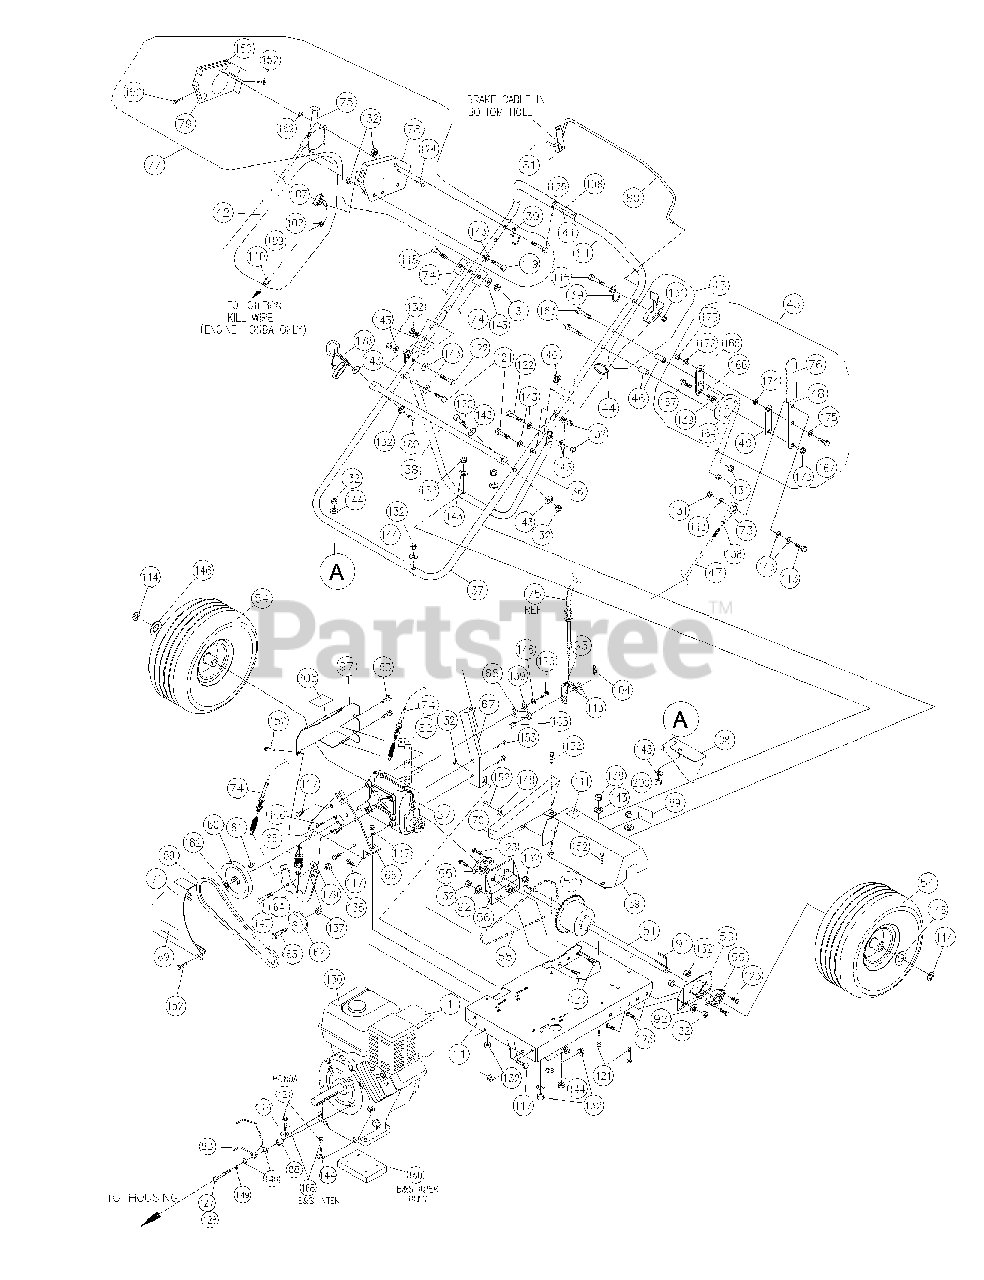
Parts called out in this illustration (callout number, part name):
1	ENGINE 10 HP INTEK B&S
2	ANGLE MOUNT HDLE WA
3	IMPELLER ASSY VQ (INCLUDES ITEM 4,5,6,7)
4	KEY 0.25 SQ. X 2.75"
5	WASHER LOCK 7/16 S/T MED
6	SCREW CAP 7/16 NF x 2 1/4 GR8 TORQ 55-60 FT LBS (75-81 N.m)
7	SPACER ENGINE
9	SCREW CAP 5/16 NF x 2 1/2 GRD. 8
10	HOUSING ASSEMBLY W/LABELS VQ
11	FRAME WA VQ
12	NOZZLE ASSEMBLY VQ
13	NOZZLE ASSY W/LABELS
14	HOSE TUBE PLUG VQ
15	PLATE DOOR NOZZLE HOSE
16	ROD DIVERTER VQ
17	GROMMET FLG. 1/2 MOLDED
18	BRKT BOGIE ASSY LH
19	BRKT BOGIE ASSY RH
20	BRKT BOGIE WA LH
21	BRKT BOGIE WA RH
22	ROLLER GUIDE
23	PIN ROLLER
24	WHEEL BOGIE 3"
25	SPACER 5/16 X 1 5/8
26	CASTER & BRKT LH ASSY SEMI-PNEU VQ
27	CASTER & BRKT RH ASSY SEMI-PNEUVQ
28	BRKT LH WA 8" CASTER
29	BRKT RH WA 8" CASTER
30	CASTER ASSY 8" SEMI-PNEU 3/4 NC (INCL ITEM 33 (4), 94, 95, 125, 134)
31	KNOB HAND
32	NUT WING WA
33	WASHER 3/4 NYLON
34	ELBOW ASSY W/LABELS VQ
35	GASKET FLANGE TRANSITION VQ
36	HANDLE BRACE REAR
37	HANDLE LOWER VQ
38	TUBE HANDLE BAG SUPPORT
39	ROD BAG LOOP
40	PLUG TUBE INSERT 1" OD
41	HANDLE ASSY UPPER W/GRIP (39, 45, 46, 81, 114, 115, 131, 163)
42	PART NOT APPLICABLE ON THIS MODEL
43	CONTROL THROTTLE ASSY VQ SERVICE
45	DOOR NOZZLE FRICTION ASSY
47	ROD DOOR NOZZLE
48	BAR LEVER DOOR
49	PLATE FRICTION LIFT
50	BAG ASSY VQ / TURF BAG 830313
51	DIFFERENTIAL ASSY
52	SPROCKET 35 TOOTH #41
53	WASHER 1.5 OD X .453 ID X .25 THK
54	WHEEL 13" x 6.5" PNEU. SP
55	BRG ASSY VQSP
56	BRKT MOUNT BEARING
57	TRANSMISSION 5 SPEED 1 REV W/BRAKE (TECUMSEH)
58	CHAIN #41 x 68P VQSP
59	BELT “V” 4L x 34" OUTSIDE LG.
60	PULLEY 5.0 DIA. A SEC 0.625 ID
61	KEY HIPRO 3/16 X 3/4
62	PULLEY IDLER
63	BOLT IDLER
64	ARM IDLER WA VQ
66	BRKT TRANSMISSION WA VQ
67	BRKT TRANSMISSION REAR WELD LONG
68	BAR LINK SHIFT OFFSET VQ
69	GUARD DIFFERENTIAL VQ WELD
70	GUARD CHAIN VQ WELD
71	GUARD PULLEY W/LABEL
72	LABEL PRODUCT DECAL LG CIRCLE
73	SPHERICAL ROD END MSF-5
74	CABLE CLUTCH ASSY
75	CONTROL SHIFT VQSP
77	CONTROL ASSY VQSP
78	BRACKET CONTROL SHIFT
79	COVER CONTROL SHIFT VQ
80	ROD BAIL CLUTCH
81	GRIP HANDLE 1" x 13"
82	BAR BRAKE CABLE MOUNT
83	WIRE BELT GUIDE VQ
84	GRIP RING
85	SPRING COMPRESSION
87	SPRING DOOR
88	PART NOT APPLICABLE ON THIS MODEL
89	LABEL DANGER GUARDS
91	KEY SQ 3/16 X 1 3/4
92	WASHER 5/16 TWISTED TOOTH
93	CLIP ASSY GEAR SELECTOR
94	FORK CASTER 8" 3/4 NC
95	PART NOT APPLICABLE ON THIS MODEL
97	GUARD BRAKE VQ
98	GUARD BELT VQ
99	LABEL DIVERTER INSTRUCTIONS
100	LABEL DANGER
101	LABEL DANGER FLYING MATERIAL
102	PART NOT APPLICABLE ON THIS MODEL
103	PIN CLEVIS
106	LABEL CLUTCH VQ
107	PART NOT APPLICABLE ON THIS MODEL
109	PART NOT APPLICABLE ON THIS MODEL
110	PART NOT APPLICABLE ON THIS MODEL
111	LABEL OIL
113	SCREW CAP 1/4-20 x 1 1/4"
114	RING RETAINING "E" 3/4
115	SCREW CAP 1/4-20 x 2"
116	SCREW CAP MACH 10-18X3/4 WF ZP
117	SCREW CAP 5/16-18 x 3/4"
118	PLATE DEBRIS DEFLECTOR
119	SCREW CAP 5/16-18 x 1 1/4"
120	SCREW CAP 5/16-18 x 1 1/2
121	SCREW CAP 5/16-18 x 1 3/4"
122	SCREWCAP 5/16-18 X 2 1/4"
123	BOLT CARRIAGE 5/16-18 X 3/4
124	SCREW #10-24NC X 5/8 HEX
125	SCREW CAP 1/2-10 x 4 1/2"
126	SCREW CAP 1/4 NF x 1/2 GR. 5"
127	PART NOT APPLICABLE ON THIS MODEL
128	SCREWCAP 5/16 NF X 1 1/2
129	SCREWCAP 5/16-18 X 2 1/4"
130	LABEL WARNING FUEL EN/SP
131	NUT LOCK 1/4 NC
132	NUT LOCK 5/16 NC
133	NUT LOCK 10-24
134	NUT LOCK 1/2"-13 LT WT TH ZP
135	NUT LOCK 3/8 NC THIN HT
136	LABEL PRODUCT DECAL VQ
137	NUT REG. 3/8 NC
138	NUT REG. 5/16 NF
139	WASHER SAE 1/4
140	WASHER SAE 5/16
141	WASHER SAE 3/8
143	WASHER FLAT CUT 1/4
144	WASHER FLAT CUT 5/16
146	WASHER 3/4 (0.765 x 1.25 x 0.06)
147	BOLT SHOULDER 3/8 X 3/4"
148	WASHER LOCK 1/4
149	WASHER LOCK 5/16
150	LABEL SPEED CONTROL
151	SCREW MACH #10-24 x 2"
152	SCREW SHT. MTL 1/4 AB x 3/4
153	SCREW SELF-TAP 5/16 NC x 3/4 HEX
154	PIN ROLL 1/8 x 3/4
155	PIN COTTER 3/32 x 3/4
156	PIN COTTER 1/8 x 1"
157	SCREW CAP 5/16-18 x 2 3/4
158	LOOSE PARTS BAG ASSY VQ
159	LABEL DANGER INSTRUCTIONS
160	SPACER ENGINE INTEK
162	DEFLECTOR DEBRIS ASSY
163	SCREW CAP 1/4-20 x 2"
164	PLATE QUAD LIFT
165	PLATE CLAMP LIFT
166	BALL 1/4"
167	SCREW CAP 1/4-20 x 1"
168	SCREWCAP 5/16-18 X 2 1/2"
169	NUT LOCK #10-24 NC LT
172	WASHER - BELVILLE 1/4"
173	NUT LOCK 1/4-20
174	NUT JAM 1/4" NC HEX
175	WASHER LOCK - EXT 1/4
178	EYEBOLT PIGTAIL 5/16-18 X 1 1/4"
179	WASHER SHIM 0.020"
180	CAP ROPE GUIDE BOLT VQ
182	SNAP RING
190	PART NOT APPLICABLE ON THIS MODEL
200	NUT 5/116" - 18 HEX ZP
205	LABEL MADE IN U.S.A.
